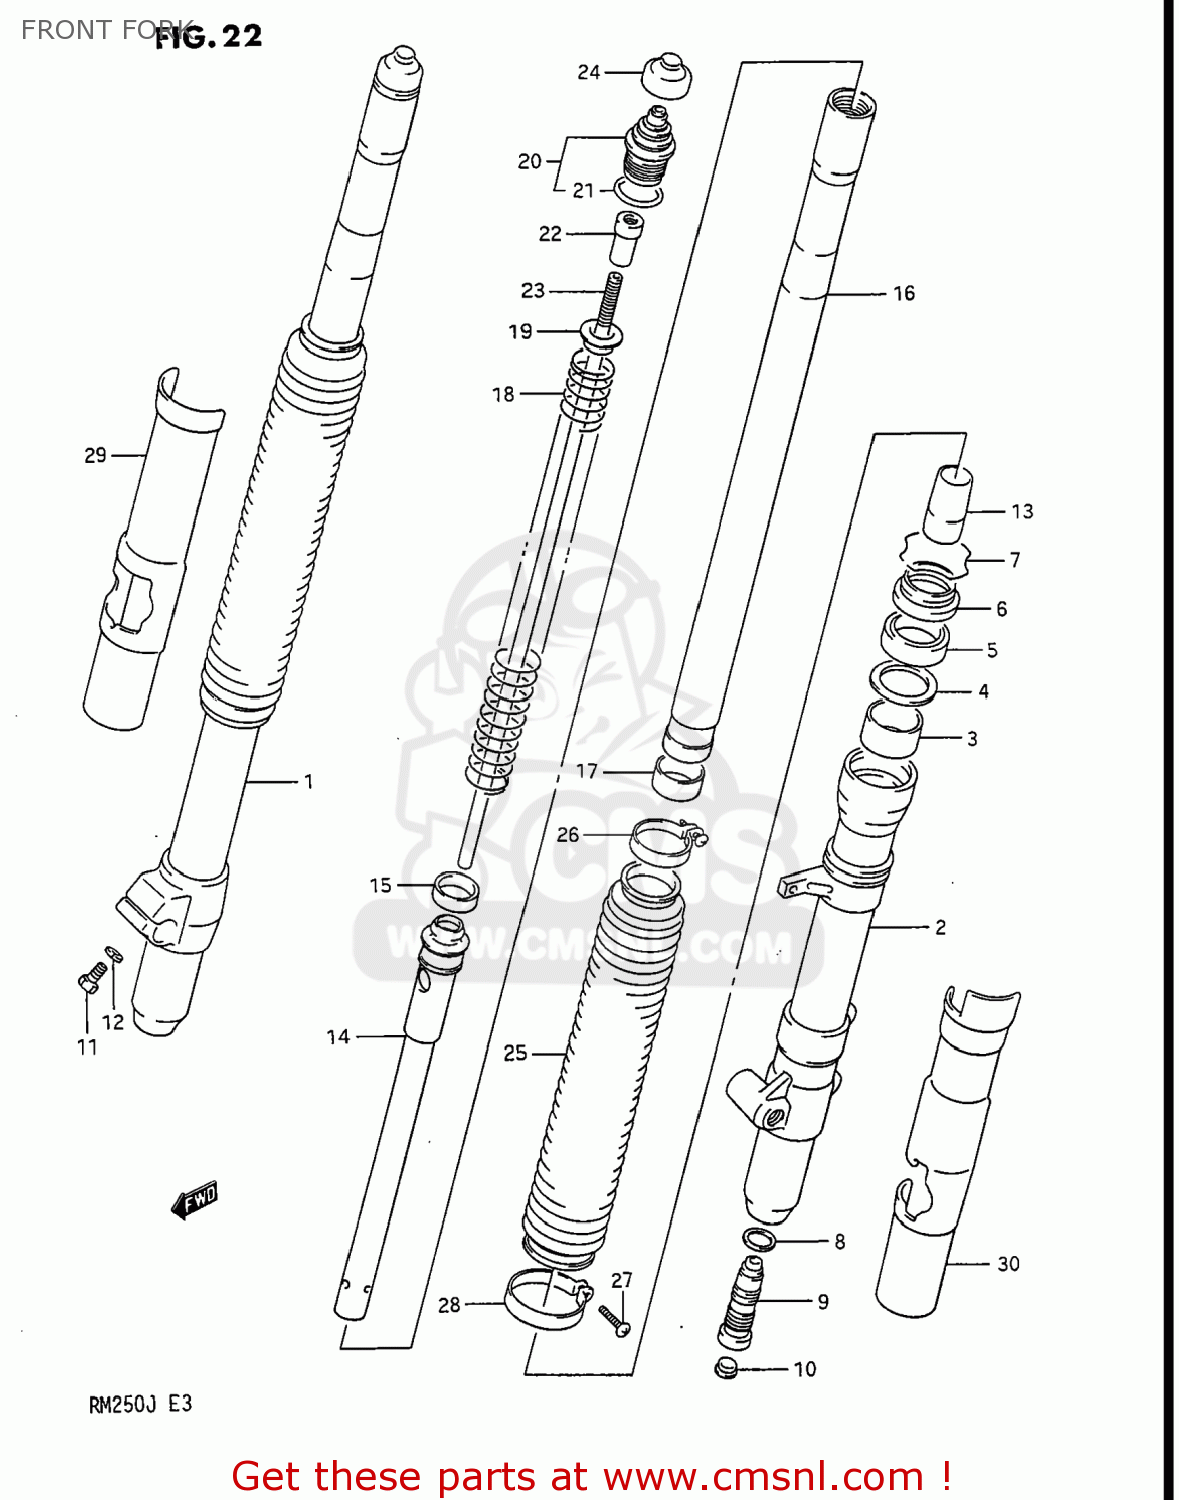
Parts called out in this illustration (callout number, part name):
1	TUBE,OUTER,RIGHT
2	TUBE,OUTER,LEFT
3	METAL,SLIDE
4	WASHER
5	OIL SEAL,FRONT FORK
6	DUST SEAL,FRONT FORK
7	RING,STOPPER
8	GASKET (NAS)
9	VALVE ASSEMBLY
10	CAP,FRONT FORK DF
11	BOLT
12	WASHER,LOCK
13	PIECE,OIL LOCK
14	CYLINDER,FRONT FORK
15	RING,FRONT FORK PISTON
16	TUBE,FORK,INNER
17	PISTON
18	SPRING
19	GUIDE,FRONT FORK SPRING
20	CAP
21	O RING
22	NUT
23	ROD,PISTON
24	CAP
25	BOOT
26	BAND,BOOT,UPPER
27	SCREW,BAND BOOT(3.5X10)
28	BAND,BOOT LWR
29	PROTECTOR,RIGHT
30	PROTECTOR,LEFT
